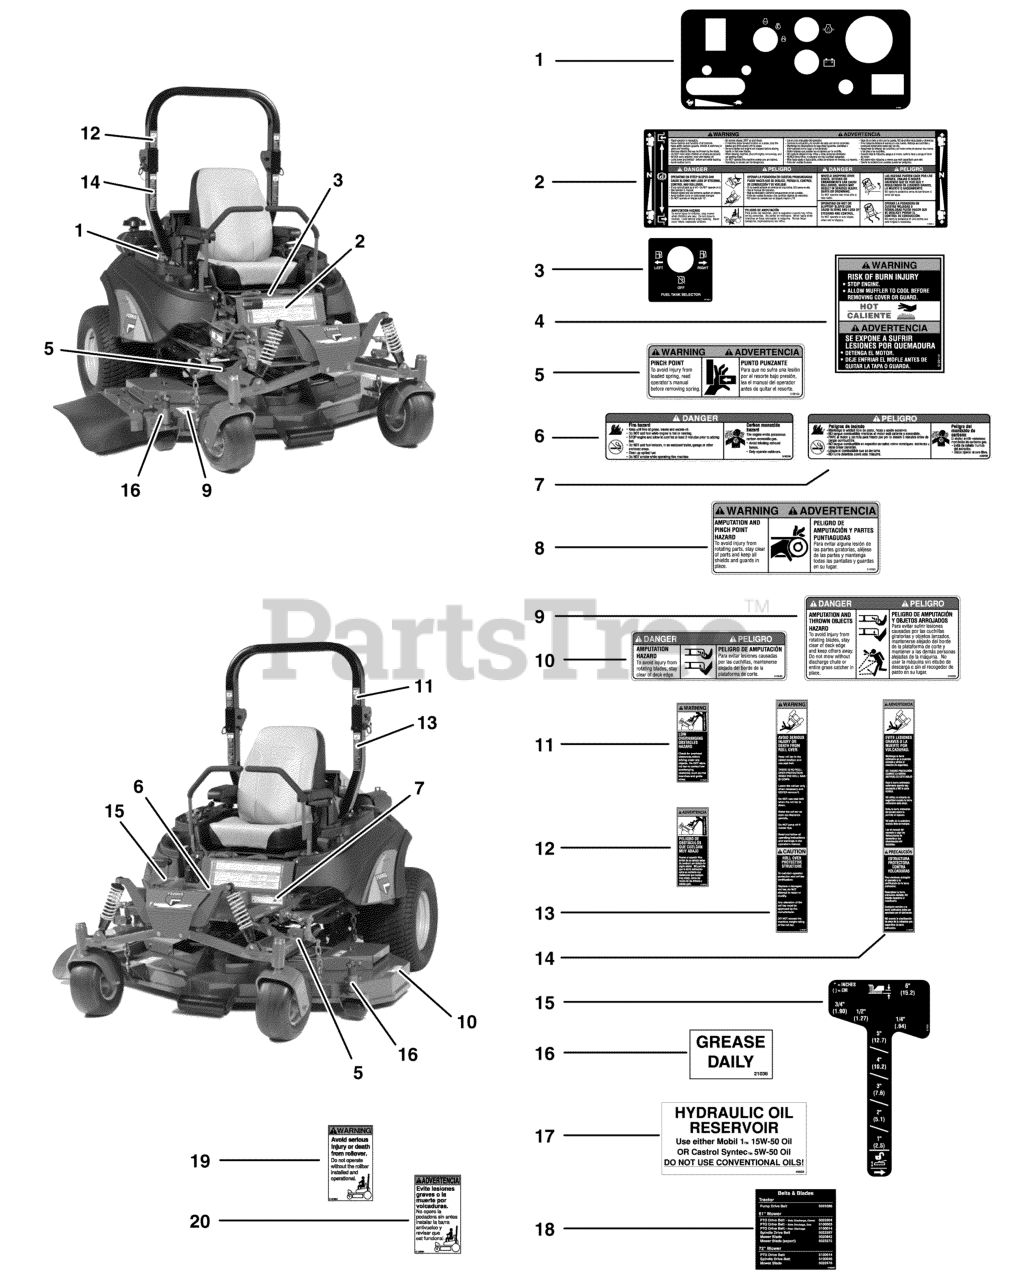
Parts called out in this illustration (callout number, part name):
1	DECAL, Control Panel, Gas
2	DECAL, Main Safety
3	DECAL, Fuel Selector
4	DECAL, Warning, Burn
5	DECAL, Pinch Point
6	DECAL, Danger, Fire
7	DECAL, Danger, Fire (SP)
8	DECAL, Warning, Hand In Pulley
9	DECAL, Danger, Mower Discharge
10	DECAL, DANGER, MOWER
11	DECAL, Warning, Overhang, ROPS
15	DECAL, Height of Cut
16	DECAL, Grease Daily
17	DECAL, Oil Reservoir
18	DECAL, Blade & Belt, IS4500Z
19	DECAL, Warning, ROLL BAR
20	DECAL, Warning, ROLL BAR (SP)
